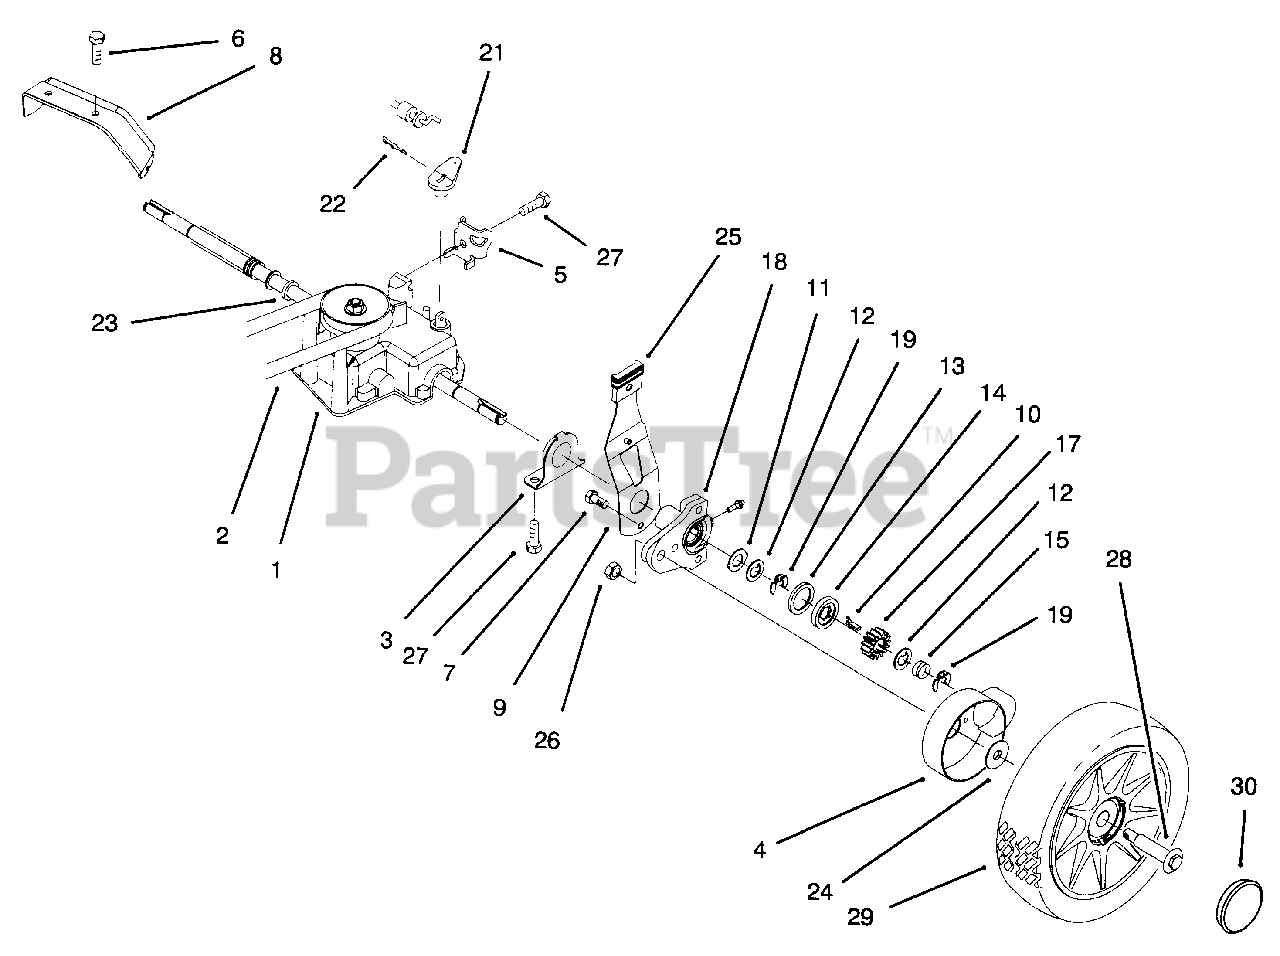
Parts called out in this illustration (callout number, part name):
1	Gear Case Assembly
4	Cover-Wheel
5	Retainer-Cable
6	Screw-Hex Hd.
7	Screw-Hex Hd.
8	Bracket-Belt Guide
9	Spring Arm Ass'y-Rear
10	Key-Rocking L.H.
11	Washer-Thrust
12	Washer-Thrust Keyed
13	Ring-Friction
15	Spring-Compression
17	Gear-Pinion
18	Arm-Pivot
19	Ring-Retaining
21	Lever-Shift
22	Pin-Cotter
24	Spacer-Cover Wheel
25	Knob-Arm
26	Nut-Lock
27	Screw-Tapping
28	Bolt-Wheel
29	Wheel & Tire Assembly
